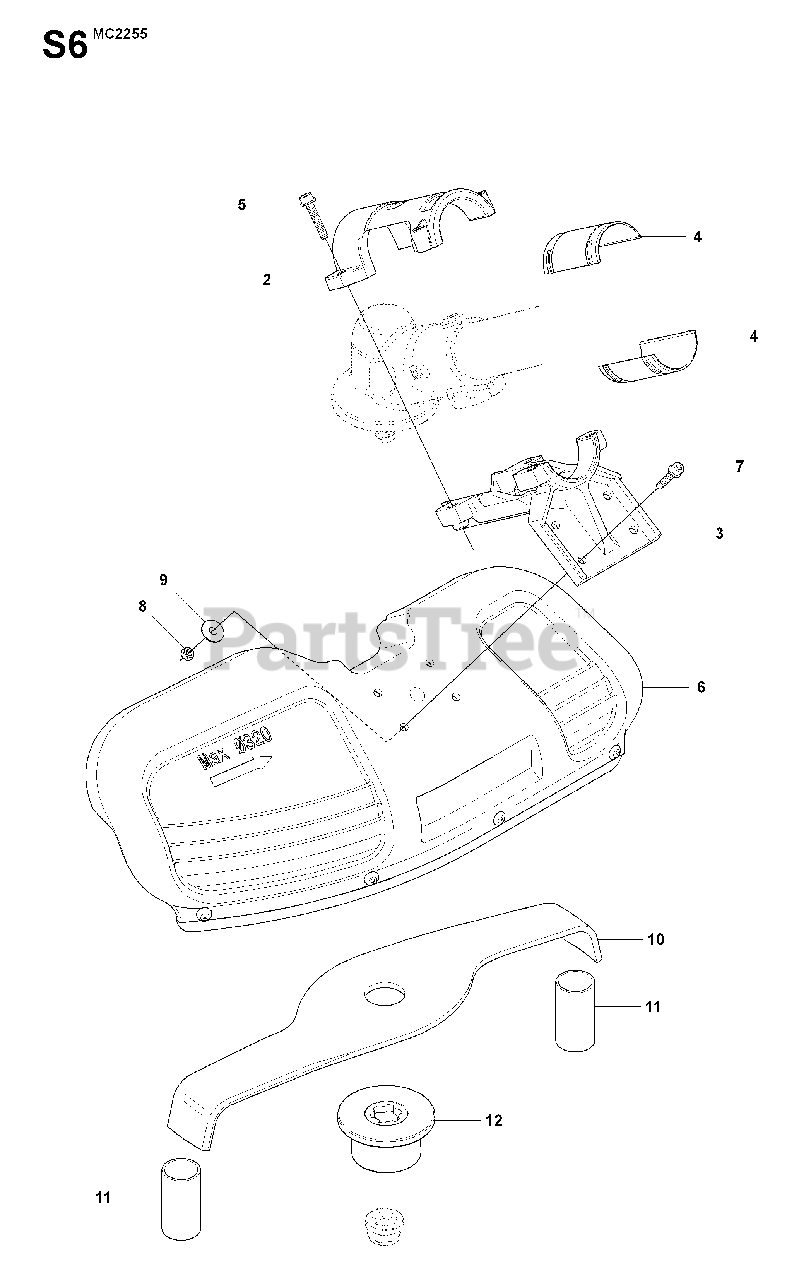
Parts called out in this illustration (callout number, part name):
8	LOCKNUT M5
11	TRANSPORT GUARD
12	SUPPORT FLANGE
